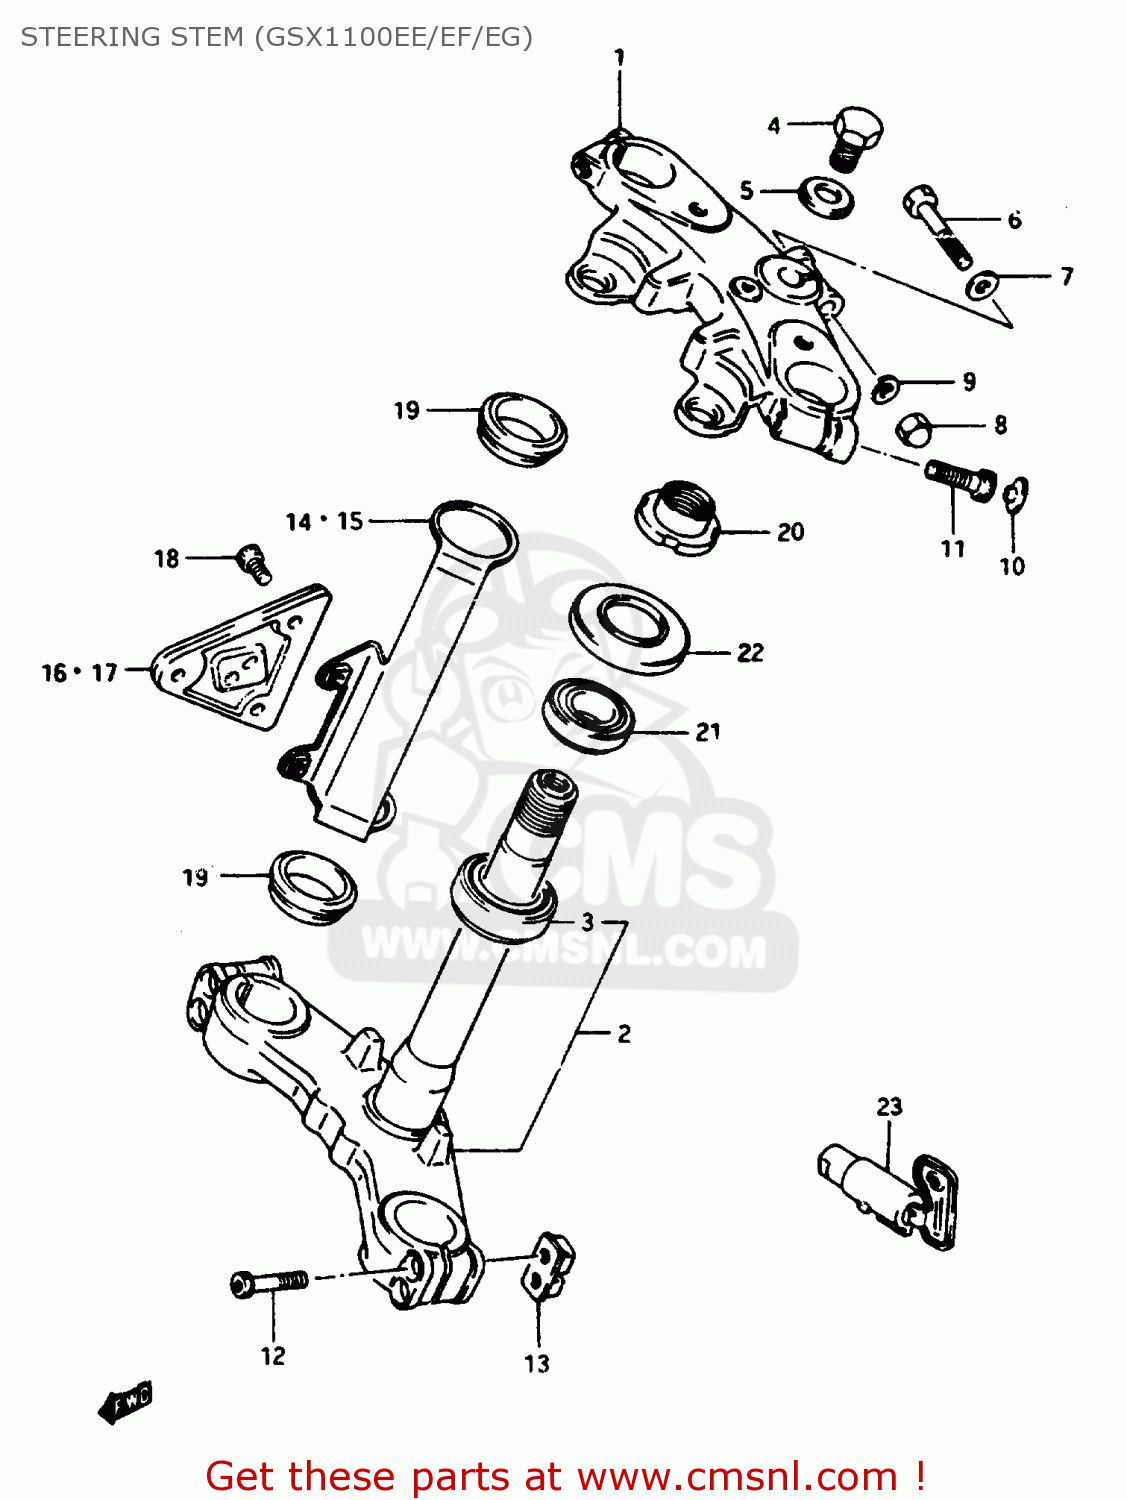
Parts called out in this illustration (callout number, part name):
1	HEAD,STEERING STEM
2	STEM,STEERING
3	BEARING
4	NUT,STEM HEAD
5	WASHER,STEERING STEM
6	BOLT
7	WASHER
8	NUT,M8X1.25X12
9	WASHER,LOCK,8.
10	CAP(OD:20)
11	BOLT,FORK INNER TUBE FITTING
12	BOLT 8X45
13	NUT,FR FORK INNER TUBE
14	COVER, FORK RH (BLACK)
15	COVER, FORK LH (BLACK)
16	BRACKET,HEADLAMP,RIGHT N
17	BRACKET,HEADLAMP,LEFT N
18	BOLT
19	CUSHION,HEADLAMP BRACKET
20	NUT,STEERING STEM
21	TAPER,ROLLER BEARING
22	DUST SEAL,STEERING UPR
23	LOCK ASSEMBLY,STEERING (NEI
